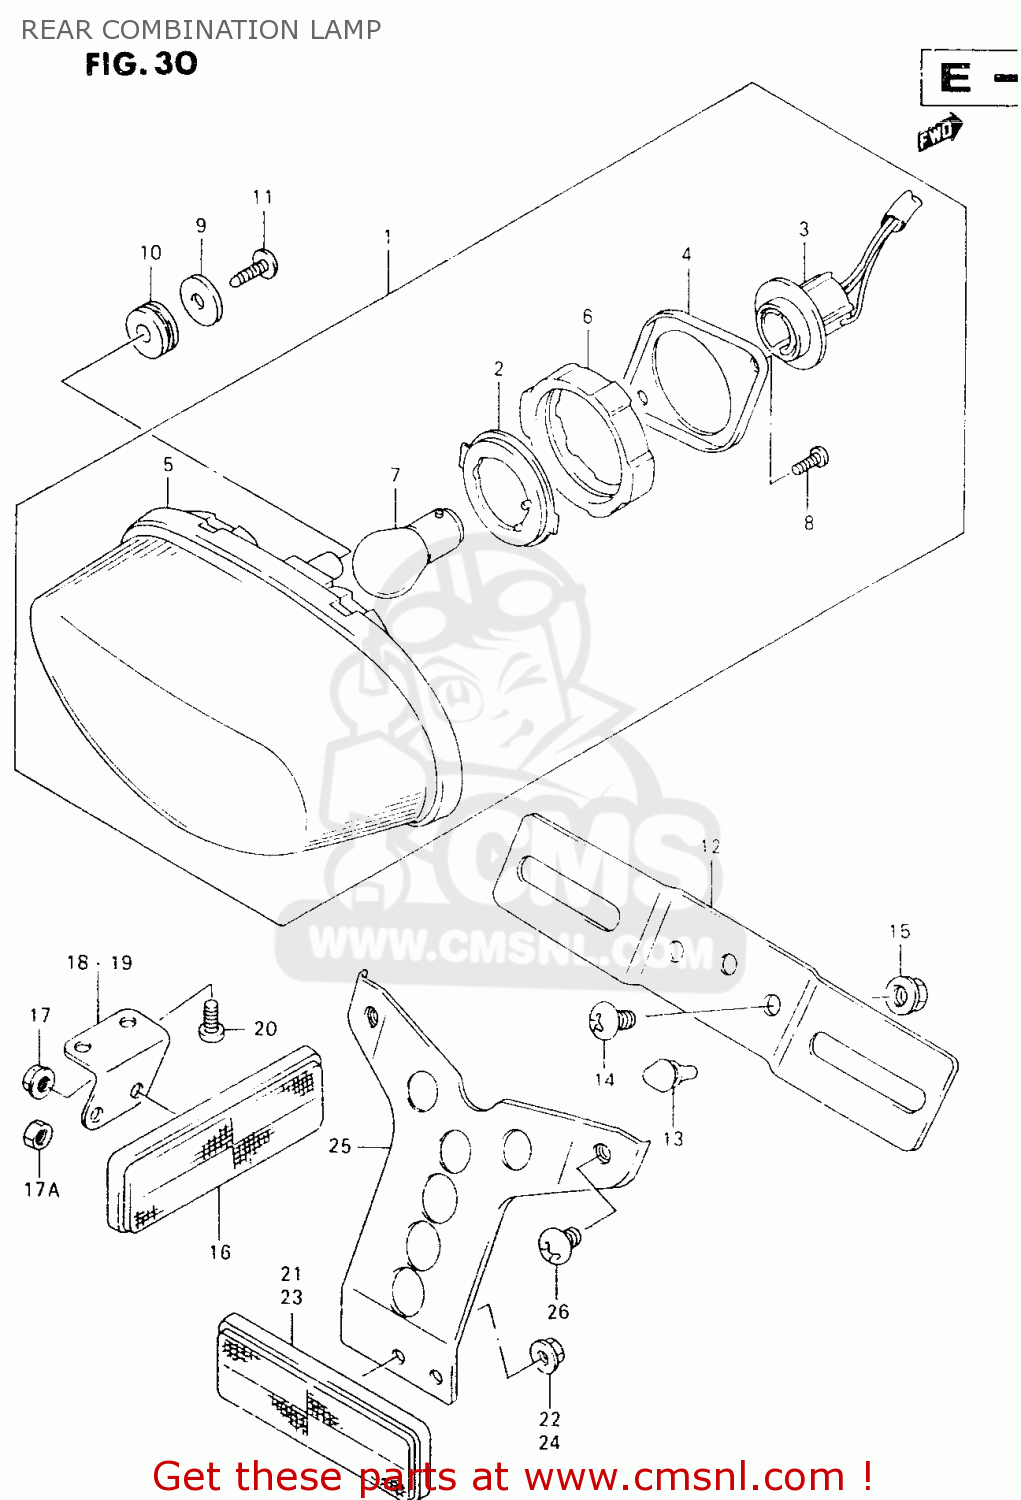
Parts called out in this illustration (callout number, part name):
1	LAMP ASSY,REAR
2	PLATE NO.1
3	SOCKET & CORD
4	PLATE NO.2
5	LAMP UNIT
6	CUSHION
7	BULB(12V21/5W)
8	SCREW
9	WASHER(5.5X20X1.2)
10	CUSHION
11	SCREW
12	PLATE,RR LICENSE
13	CUSHION
14	SCREW 6X12
15	NUT
16	REFLEX REFLECTOR,FR SIDE
17	NUT
17A	NUT
18	BRACKET,RR SIDE RR,L
19	BRACKET,RR SIDE RR,R
20	SCREW
21	REFLECTOR ASSY,RR
22	NUT
23	REFLECTOR ASSY,RR
24	NUT
25	BRACKET,RR REFLECTOR
26	SCREW 6X12
